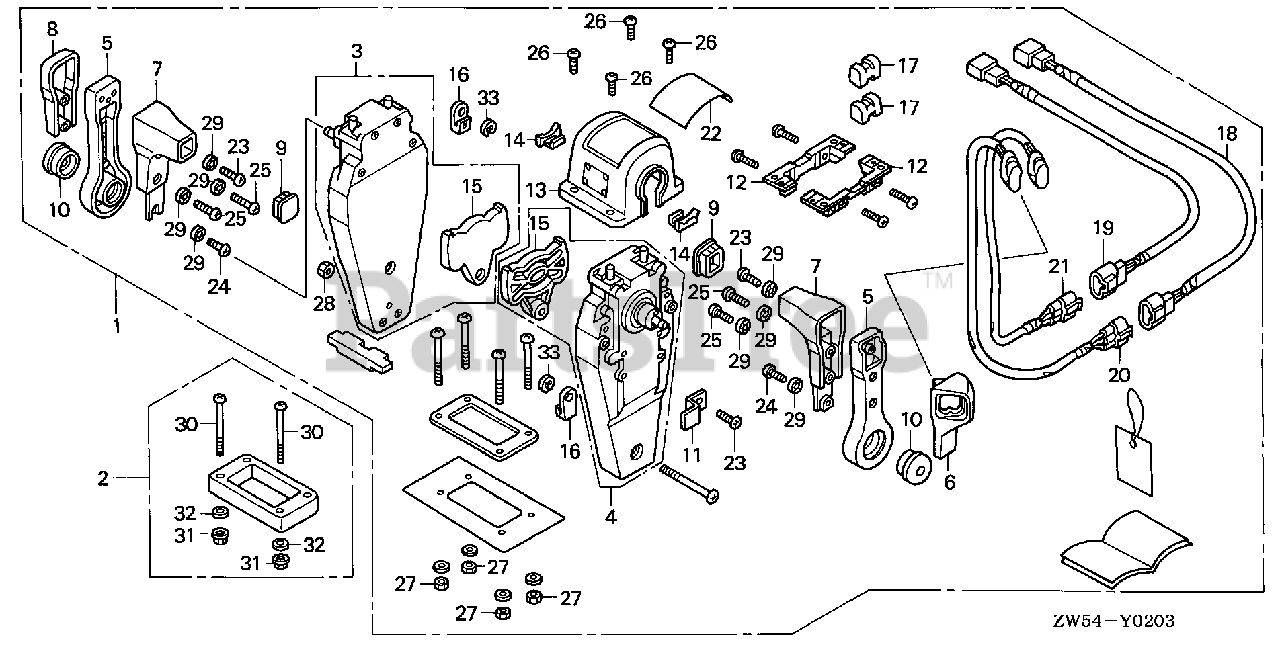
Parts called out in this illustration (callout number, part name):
1	BOX KIT, REMOTE CONTROL
2	SPACER KIT, REMOTE CONTROL BOX
3	HOUSING ASSY., L. (INNER)
4	HOUSING ASSY., R. (INNER)
5	HANDLE, REMOTE CONTROL
6	COVER, R. GRIP
7	GRIP, REMOTE CONTROL HANDLE
8	COVER, DUAL GRIP
9	CAP, GRIP
10	BUTTON, THROTTLE
11	PLATE, CABLE CLAMP
12	BRACKET, REMOTE CONTROL
13	HOUSING, DUAL REMOTE CONTROL
14	HOUSING, LEAD
15	PLATE, DWELL
16	TERMINAL, CABLE
17	SPACER, CABLE CLAMP
18	SUB-HARNESS ASSY., POWER
19	SUB-HARNESS ASSY., POWER
20	SWITCH ASSY., POWER TRIM-TILT
21	SWITCH ASSY., POWER TRIM-TILT
22	MARK, REMOTE CONTROL (DUAL)
23	SCREW, PAN (5X16)
24	SCREW, PAN (5X10)
25	SCREW, PAN (5X20)
26	SCREW, PAN (4X10)
27	NUT, HEX. (5MM)
28	NUT, HEX. (5MM)
29	WASHER, LOCK (5MM)
30	SCREW, PAN (5X65)
31	NUT, FLANGE (5MM)
32	WASHER, PLAIN (5MM)
33	E-RING (6MM)
